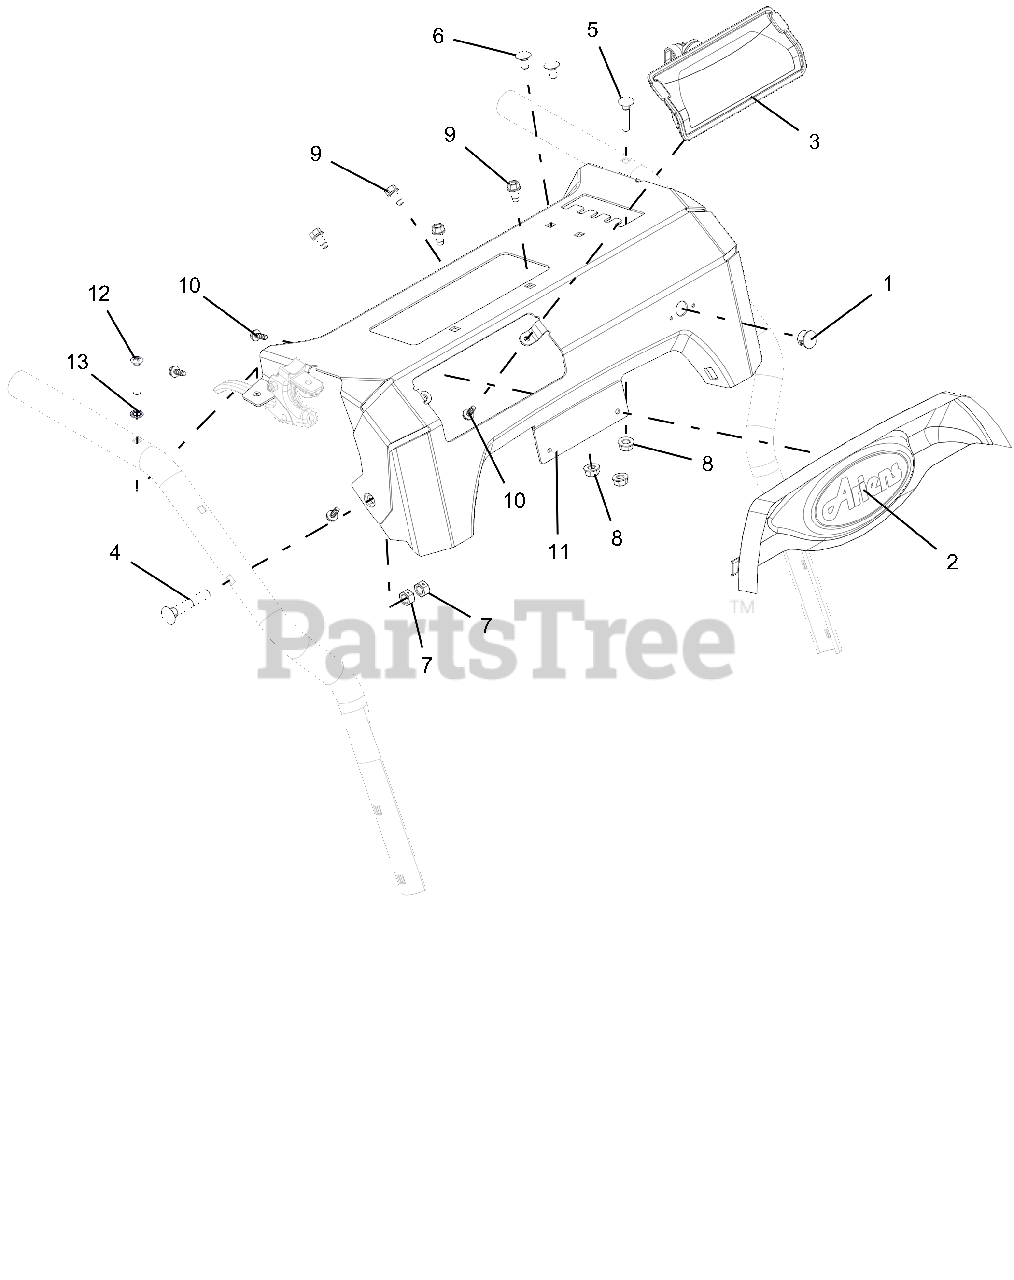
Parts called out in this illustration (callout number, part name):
1	HOLE PLUG, PLASTIC .56 HOLE
2	DASH BEZEL, ARIENS LOGO - COMP
3	HEADLIGHT ASY, HALO 20W 2SHOT
4	BLT-RDHDXLSQNK .31-18X2.0 G5YZ
5	BLT-RDHDXLSQNK.25-20X1.25 G5ZC
6	@BLT-RDHDSQNK .25-20X.50 G5YZ
7	@NUT-LK-CTR .31-18 YWZC
8	@NUT-LK-TOP-FLG .25-20 YWZC
9	SCR-TAP .25-20X.50 HWH TR YWZ
10	SCR-TAP #10X.50 BOSS INDHXHD
11	CONTROL PANEL W/DECAL, CMPT TK
12	SCR-MCH .25-20X1.50 OVAL HD
13	WSHR-LK-INT .250 TH TYA
